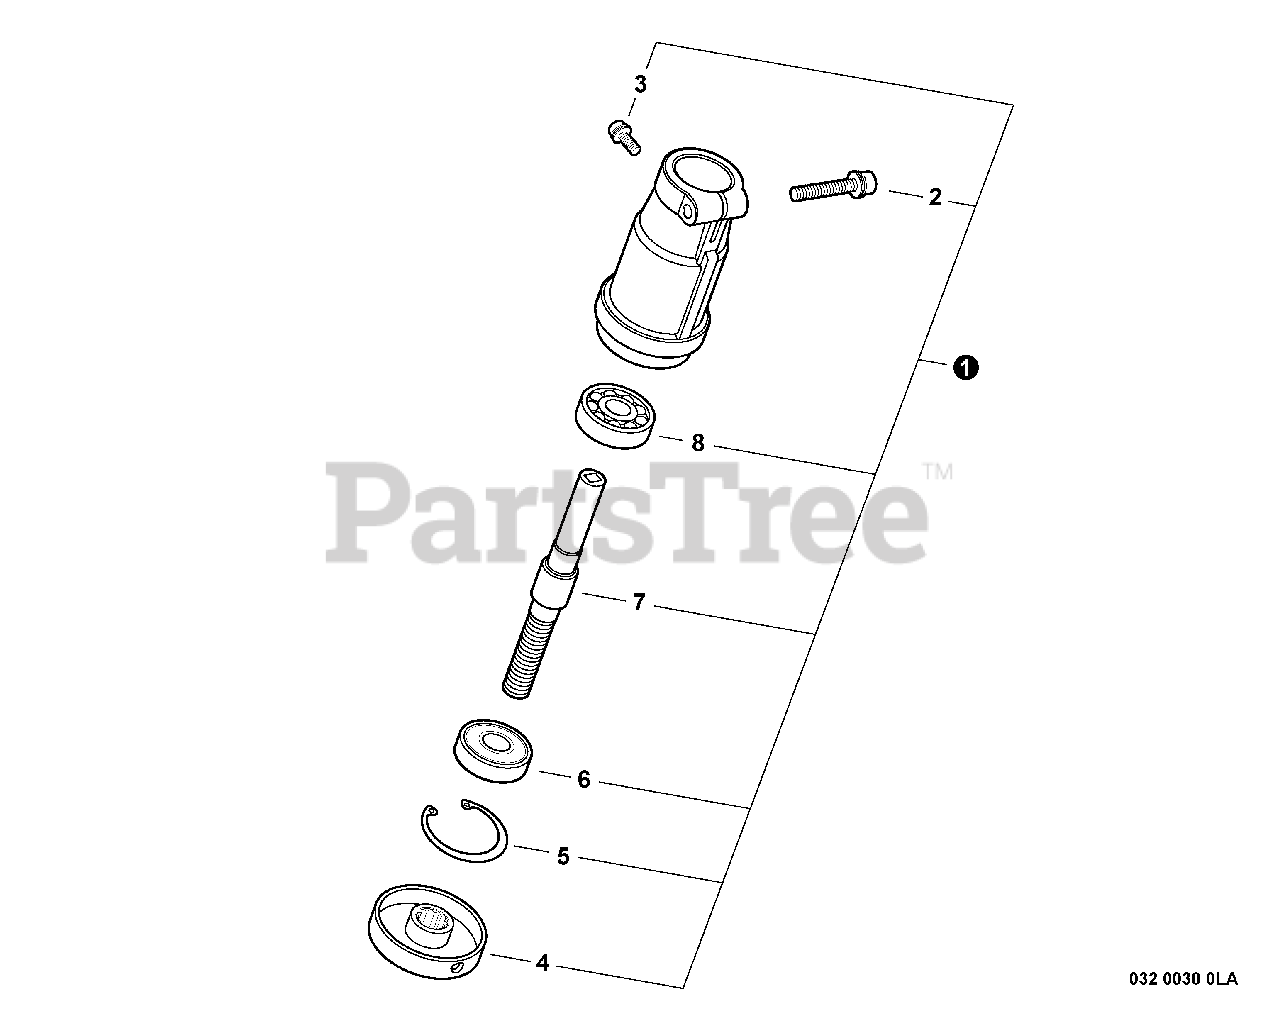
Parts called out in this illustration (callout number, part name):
1	GEAR CASE ASSY
2	SCREW - 5X25
3	SCREW - 4X10
4	ADAPTOR, BLADE - UPPER
5	RING, RETAINING - 30
6	BEARING, BALL - 6200
7	GEAR - SHAFT
8	BEARING, BALL - 6200
